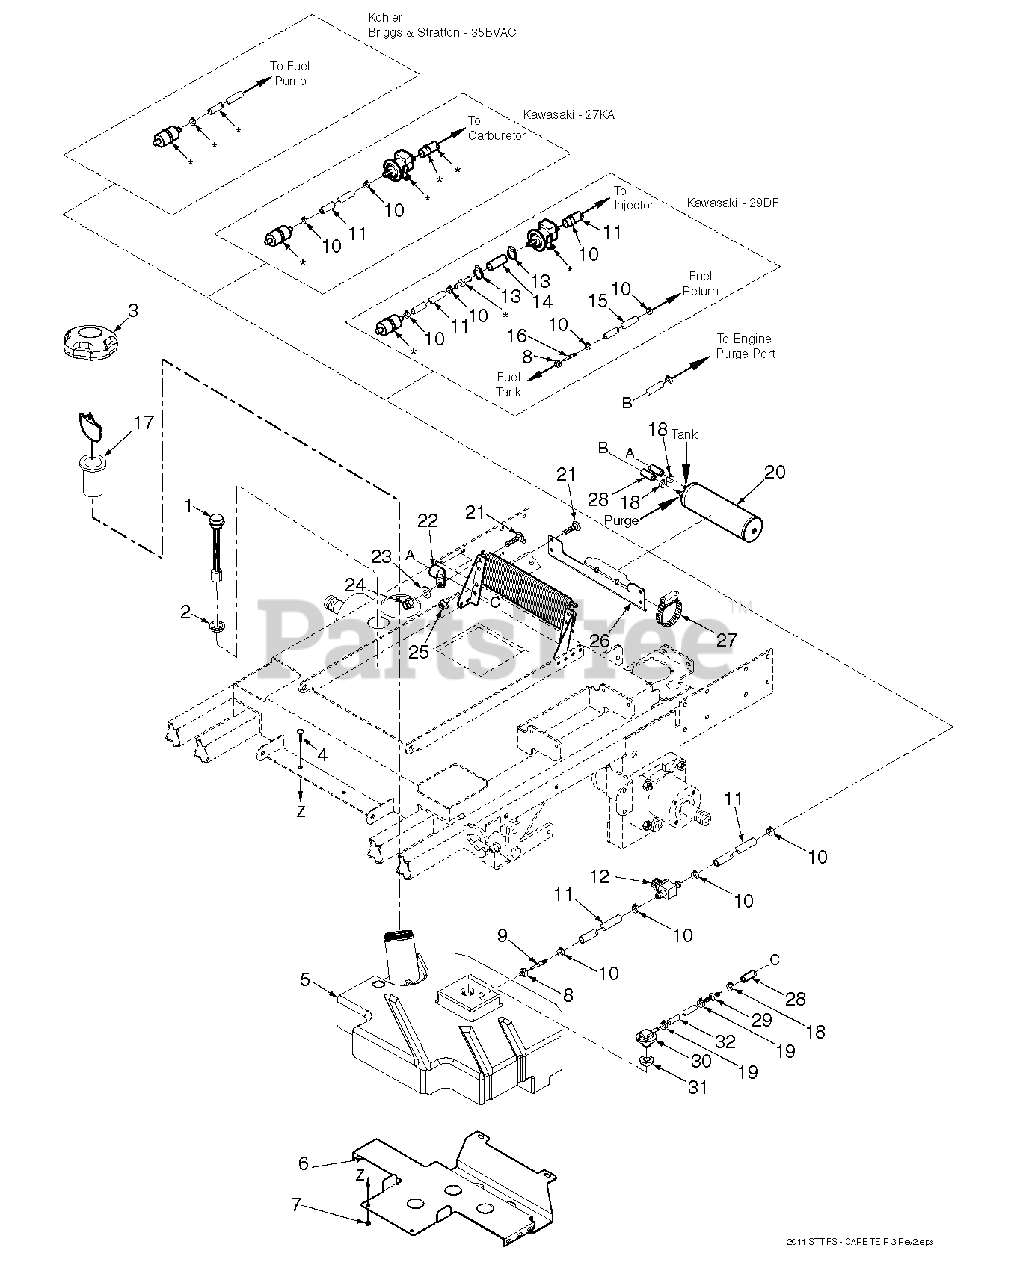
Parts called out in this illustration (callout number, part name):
1	Fuel Gauge Assembly
2	Seal, Fuel Gauge
3	Fuel Cap, Tethered
4	Bolt, Carriage 1/4-20 x 3/4"
5	Fuel Tank Assembly - STT
5	Fuel Tank Assembly - STT-DFI / EFI
6	Support Bracket, Fuel Tank
7	Nut, 1/4-20 Serrated Flange
8	Bushing, .56 Dia. Viton
9	Hose Fitting
10	Clamp, Fuel Hose 5/16" I.D.
11	Fuel Hose, 5/16" I.D. Non-Perm
12	Valve, Fuel Shut-Off
13	Clamp, .87" Max. Dia
14	Fuel Hose, 1/2" I.D. Non-Perm
15	Fuel Hose, 1/4" I.D. Non-Perm
16	Return Fitting, Straight
17	Tube, Fuel Tank Insert - 6"
18	Clamp, Vapor Recovery Hose 3/16"
19	Clamp, Fuel Hose 7/32 ID
20	Carbon Canister
21	Bolt, Carriage 1/4-20 x 3/4"
23	Flatwasher, 1/4-.281 x .562 x .049
24	Nut, 1/4-20 Elastic Stop
25	Nut, 1/4-20 Serrated Flange
26	Bracket, RH Canister Mounting
28	Hose, 3/16
29	Mender, 1/4 x 3/16 w/.02 Hole
30	Valve, Rollover
31	Grommet, Viton
32	Hose, 1/4" Vapor Recovery
